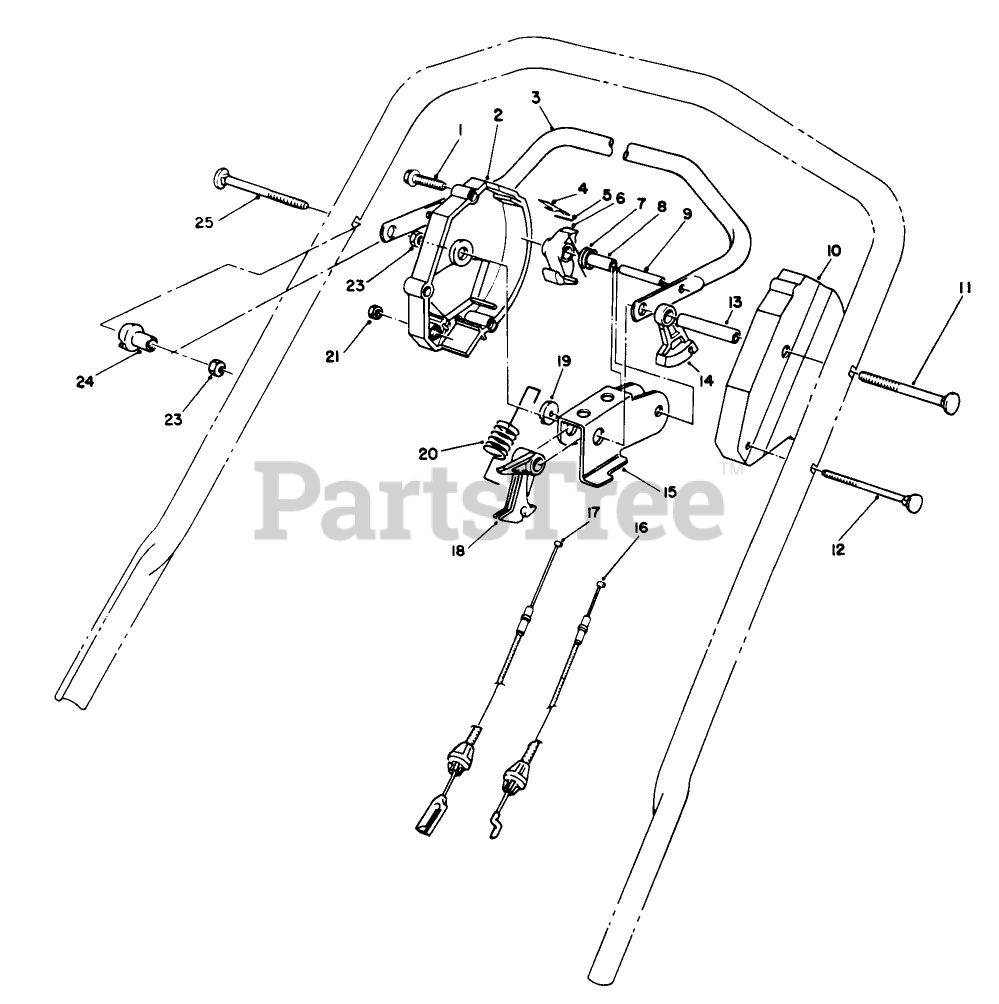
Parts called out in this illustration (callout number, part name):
1	SCREW-HWHTF
4	SPRING-LEAF
5	PIN-INSERT
6	HOOK-CONTROL
7	SPRING-TORSION
8	SPACER
9	PIN-ROLL, SLOTTED
12	HANDLE SCREW
13	TUBING-SPACER
14	LEVER-TRACTION
16	TRACTION CABLE
17	BBC CABLE ASSEMBLY
18	LEVER-CABLE
19	WASHER-NYLON
20	SPRING-DETENT
21	NUT-HEX
23	NUT-LOCK, NI
24	SPACER-SUPPORT
25	SCREW-HANDLE
